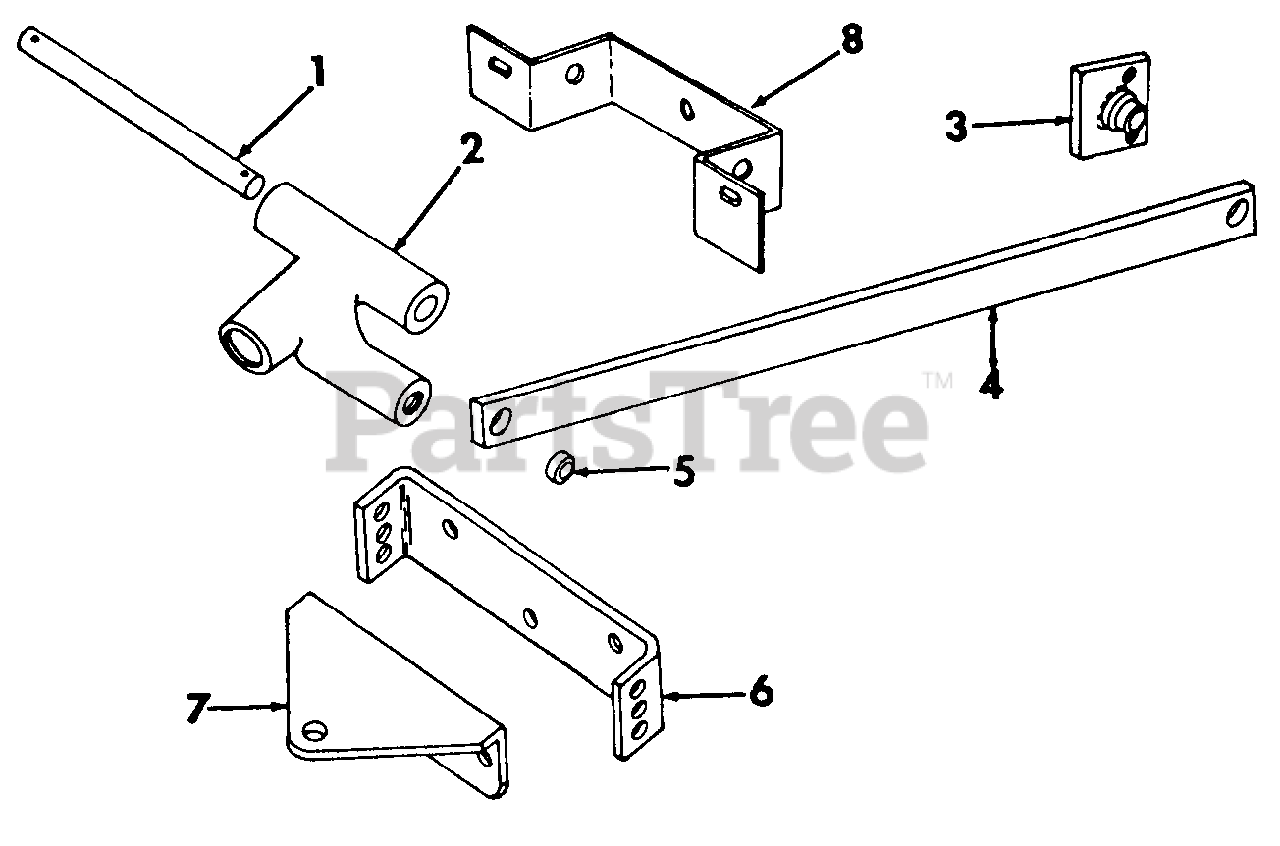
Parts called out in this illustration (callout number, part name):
1	Shaft, Lift Lever
3	Plate Assy, Lift Bar Attaching
5	Spacer, Lift Bar
7	Drawbar, Fixed
8	Bracket, Lift Lever Mounting
